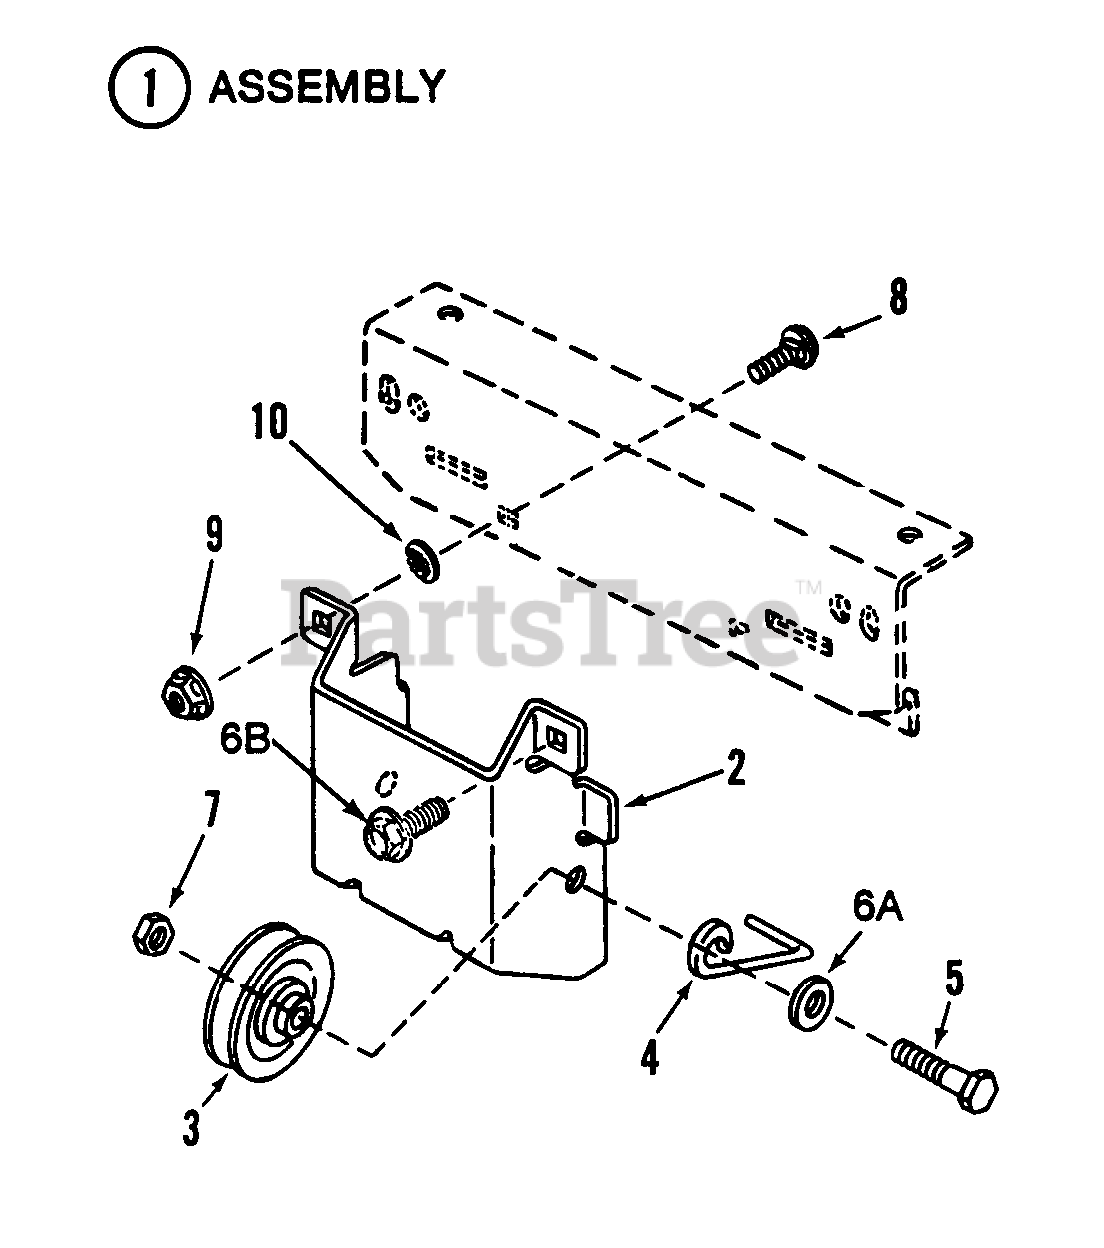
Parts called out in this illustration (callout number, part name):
1	ASSEMBLY, Mule Drive
2	BRACKET, Mule Drive
3	PULLEY, Belt Idler
4	FINGER, Belt Guide
5	SCREW, 3/8-16 x 1-1/2" Hex Head Cap, Grade 5
6A	WASHER, 3/8" Flat
6B	BOLT, 3/8-16 x 3/4" Hex Flange Lock
7	NUT, 3/8-16 Hex Top Lock
8	BOLT, 3/8-16 x 3/4" Sq. Neck, Gr. 2
9	NUT, 3/8-16 Hex Flange Lock
10	RETAINER, 3/8 Bolt
